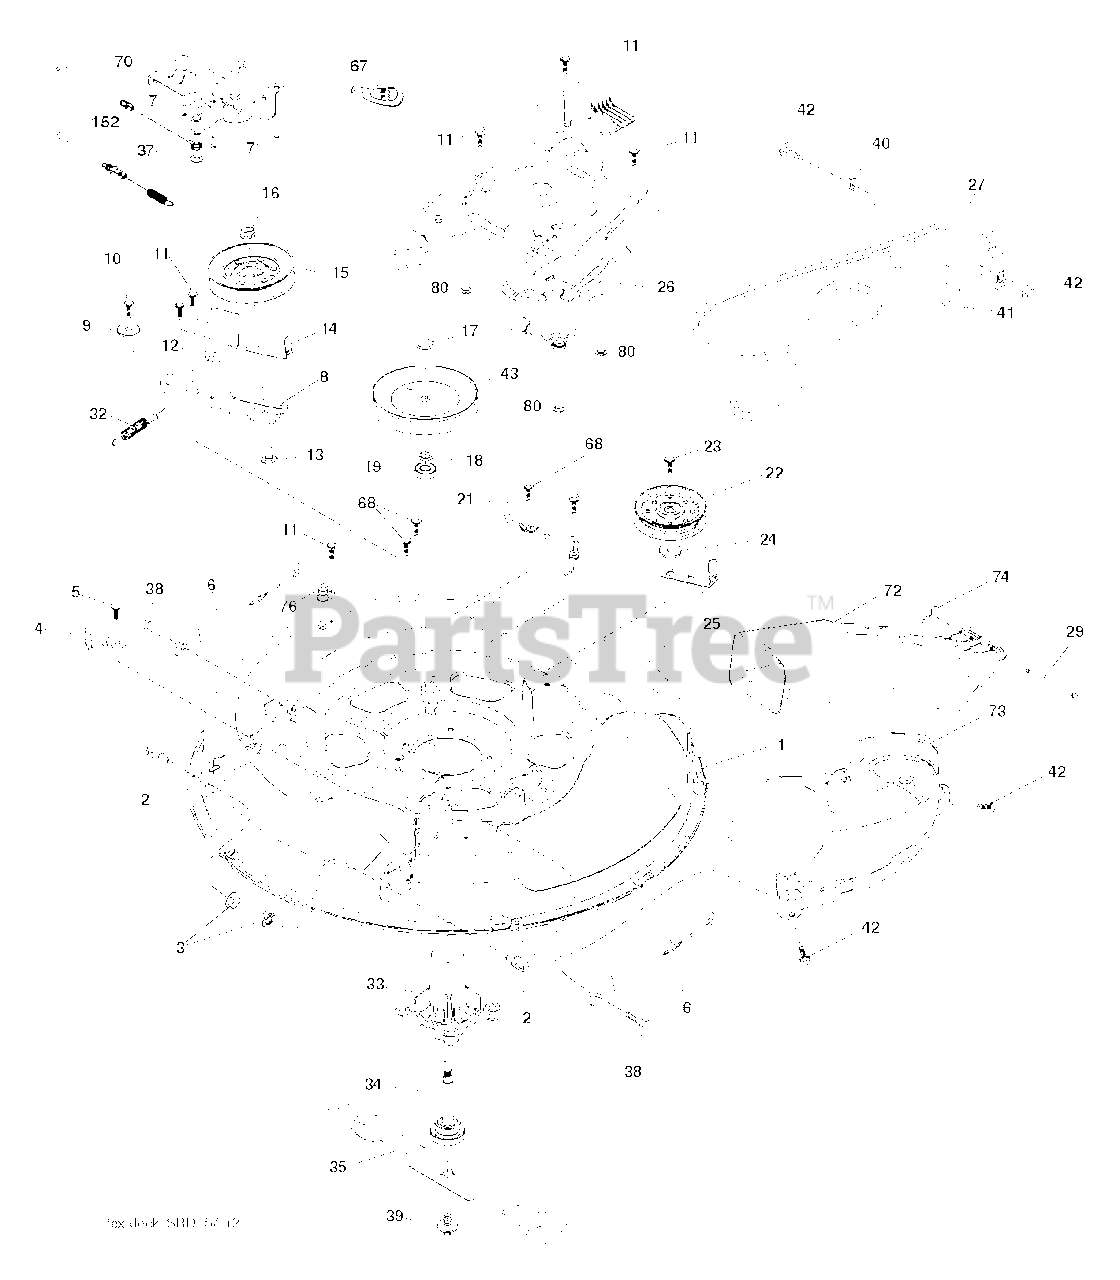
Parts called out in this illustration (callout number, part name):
1	DECK.WELDMENT.PNT.30"SRD
2	STUD.FASTNER.W/ANTI-ROTATE
3	NUT LOCK HEX FLANGE 5/16-18
4	BRACKET.CLUTCH.CABLE
5	BOLT.5/16HEX.WHS.HD
6	ARMS.SUSP.MOWER.REAR.SRD
7	SCREW.#10 X 0.750.BOS
8	ARM.IDLER.30"SRD
9	SPACER.RETAINER
10	SCREW 3/8-16X1
11	SCREW.1/4-20X5/8
12	RP ARM.BRAKE.MOWER.38"LH.TEX
13	BOLT.3/8-16X1.50
14	KEEPER, BELT IDLER
15	PULLEY.IDLER.4.25
16	NUT LOCK FLG 3/8-16 UNC
17	NUT.FLANGE.LOCK.TOP
18	WASHER.SPACER.MANDREL
21	KEEPER.BELT.MANDREL.30"
22	PULLEY.IDLER.FLAT.46.PR.DR.
23	SCREW LT
24	WASHER
25	KEEPER.BELT.30"SRD
26	COVER.ASM.MANDREL.30"
27	V-BELT.DRIVE.MOWER.30"
29	PIN.HINGE.30".SRD
32	SPRING RETURN
33	HOUSING.MANDREL.4PT.
34	SHAFT.ASM.MDRL.N/GREASE.38
35	BLADE.MOWER.BAGGING.30"
37	WASHER
38	BOLT.SHOULDER
39	SCREW.SEMS.7/16-20X1.HEX.HEAD
40	KEEPER.BELT.ENGINE.LH.LT.SRD
41	KEEPER.BELT.ENGINE.RH.LT.SRD
42	SCREW, 3/8-16X3/4
43	PULLEY, MANDREL 6.5 PD
67	HANDLE.CLUTCH.CABLE.LT
68	BOLT.HEX.WASHR.HED.313-18X1.19
70	CLUTCH.ASM.MANUAL.LT.PRED
72	CHUTE.UPPER.SRD.30R"
73	CHUTE.LOWER.SRD.30R"
74	Retainer Spring
76	PORT.WASHOUT
80	PALNUT 1/4
152	CABLE.CLUTCH.MANUAL.
